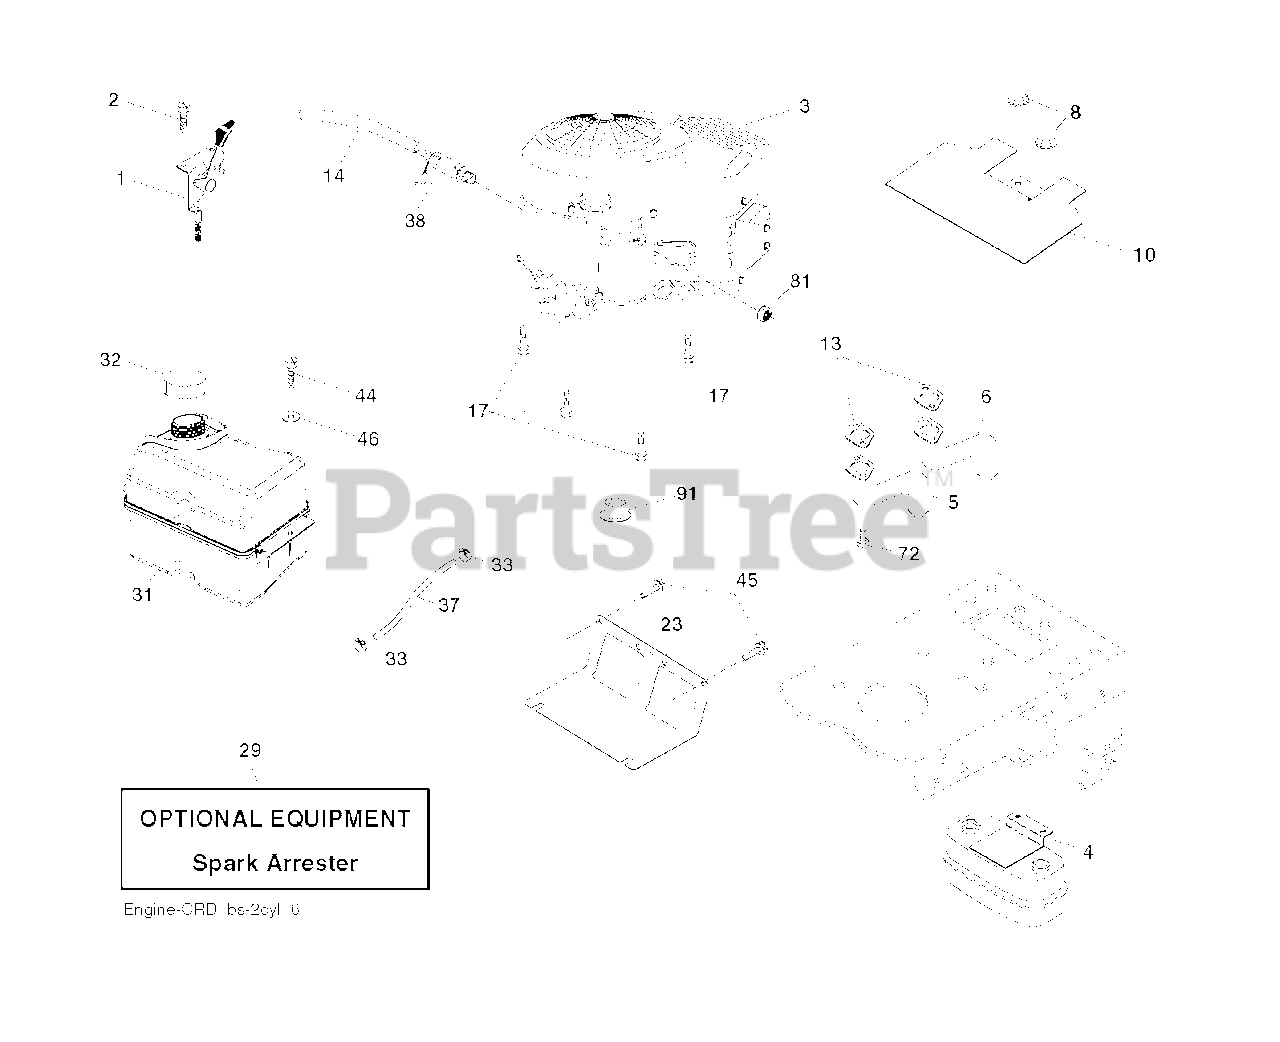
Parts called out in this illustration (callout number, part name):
1	CONTROL.TH/CK.COBRA.B&S.TWN.
2	SCREW.#10 X 0.750.BOS THREAD
4	MUFFLER.TWIN.CYL.LOW.TONE
5	EXHAUST TUBE RH
6	TUBE MANIFOLD LH
8	BOLT, 5/16-18 X 1 3/4
10	RP SHIELD HEAT MUFFLER
13	GASKET.MUFFLER
14	TUBE, DRAIN OIL ASM.
17	SCREW.3/8-16
23	SHEILD.BROWNING.DBR.GUARD
29	ARRESTER SPARK (OPTIONAL)
32	CAP.FUEL.2.25"VENTED"
33	HOSE CLAMP
37	LINE.FUEL.20
38	PLUG DRAIN OIL EASY
44	SCREW HEXWSHR 1/4-20X3/4
45	SCREW, 3/8-16X3/4
72	SCREW.SOCKET.HEAD.5/16-18
81	NUT
